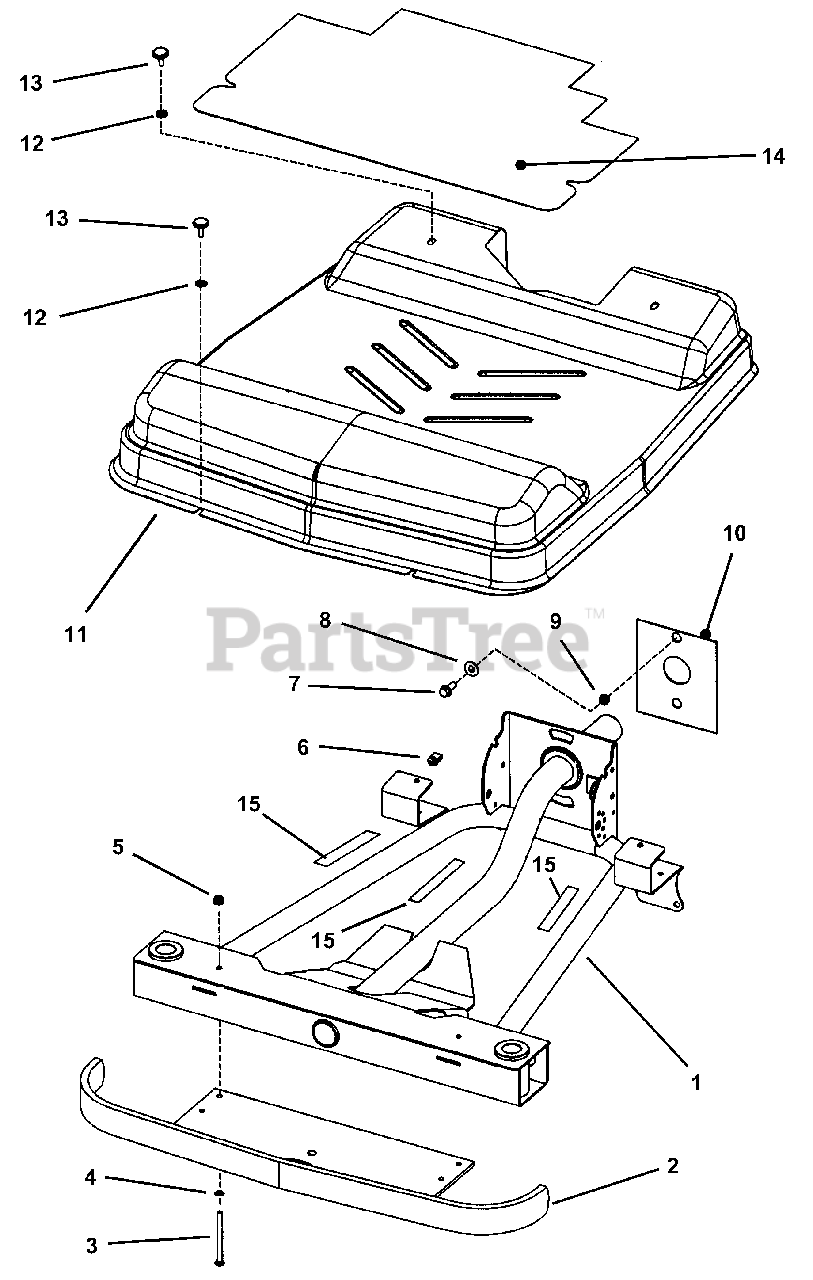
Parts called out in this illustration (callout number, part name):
1	FRAME, Front
2	BUMPER, Front
3	BOLT, 5/16-18 x 3-3/4"
4	WASHER, 5/16" Split Lock
5	NUT, 5/16-18 Hex Flange Lock, Grade 5
6	FASTENER, "U" Type 1/4"-20
7	SCREW, 3/8-16 x 1" Hex Washer Face, Self-Tap
8	WASHER, 3/8" Flat
9	SPACER, Front Frame Pivot
10	PLATE, Front Frame Pivot
11	FLOOR, Front Frame
12	WASHER, 1/4" Internal/External Lock
14	FLOOR MAT
15	PAD, Floor Pan
